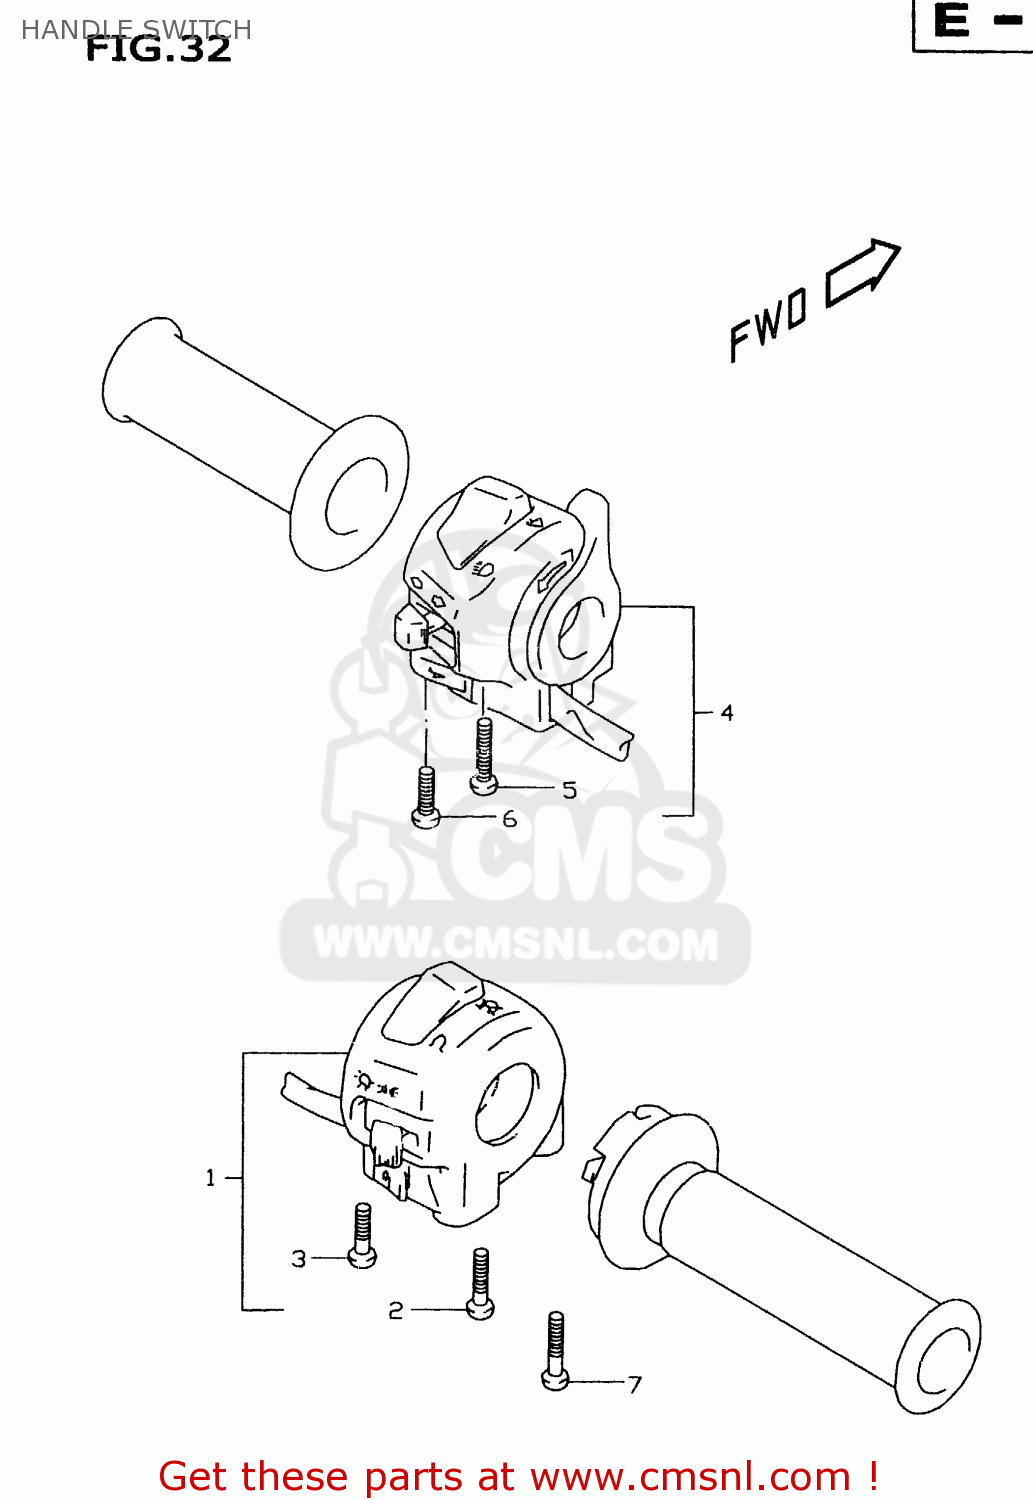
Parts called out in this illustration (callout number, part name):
1	SWITCH ASSY,HANDLE,R
2	SCREW
3	SCREW
4	SWITCH ASSY,HANDLE,L
5	SCREW
6	SCREW, 5X45
7	SCREW
